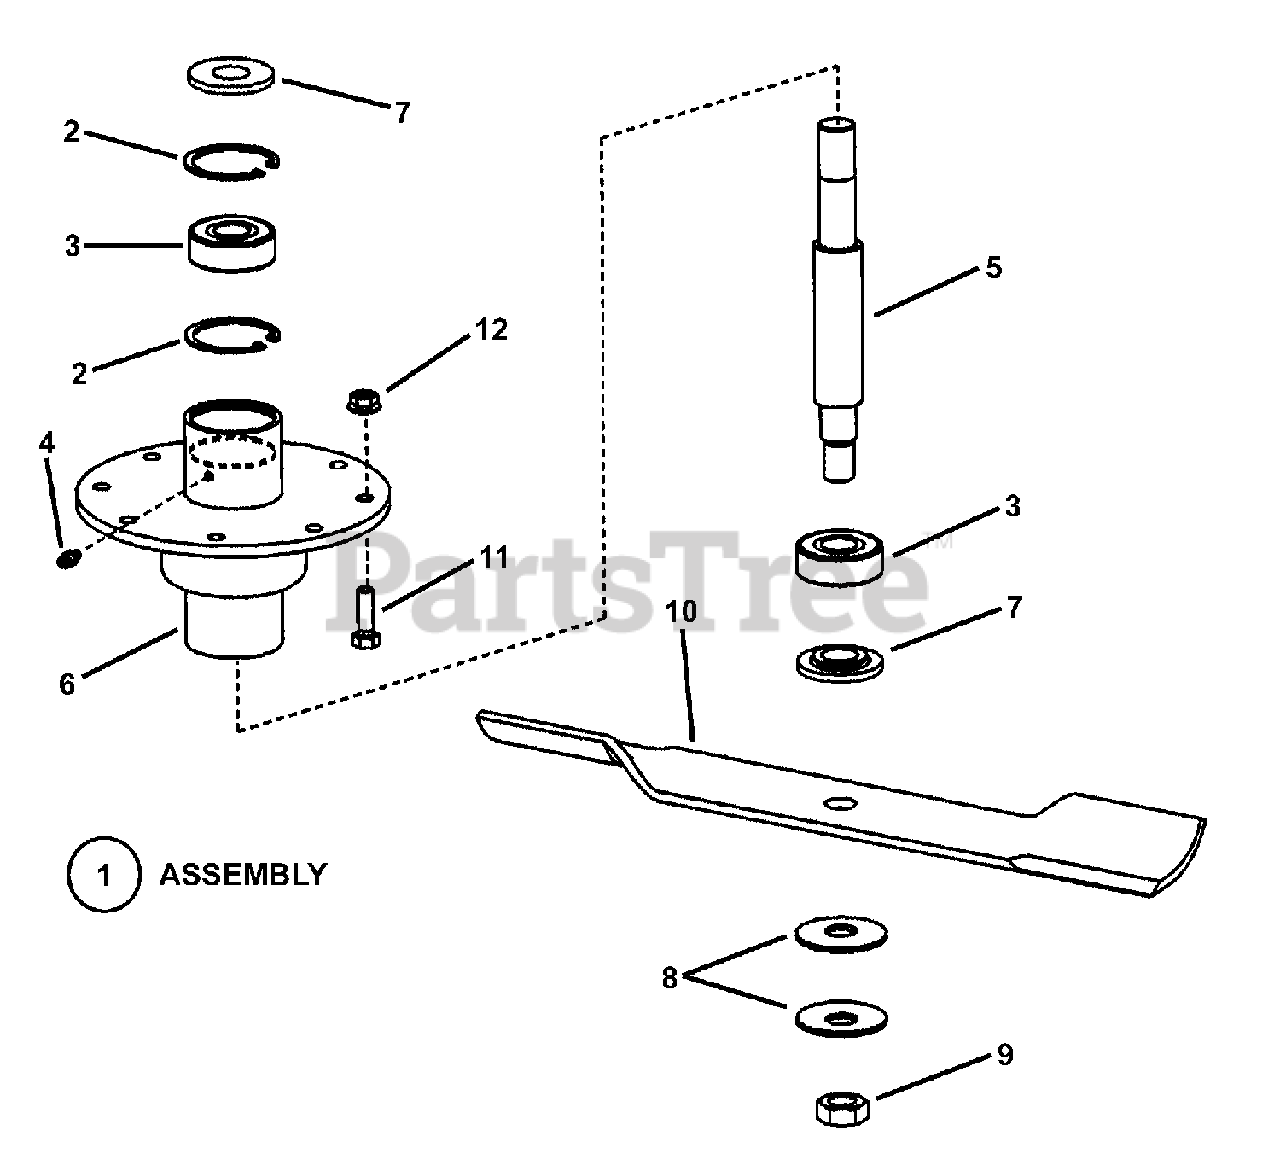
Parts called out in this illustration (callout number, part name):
1	ASSEMBLY, 48" Spindle
2	RING, 1-3/4" External Retaining
3	BALL BEARING, 3/4" I.D.
4	LUBE FITTING, Press-In (for .187 dia. Hole)
5	SHAFT, Spindle (7.81" long)
6	WELDMENT, 48" Spindle Housing
7	WASHER, Spindle
8	WASHER, .656 Belleville
9	NUT, 5/8-18 Hex Jam
10	BLADE, 16-1/2" Low Inertia
11	SCREW, 5/16-18 x 1" Hex Head Cap, GR 5
12	NUT, 5/16-18 Hex Flange Lock, GR 5
